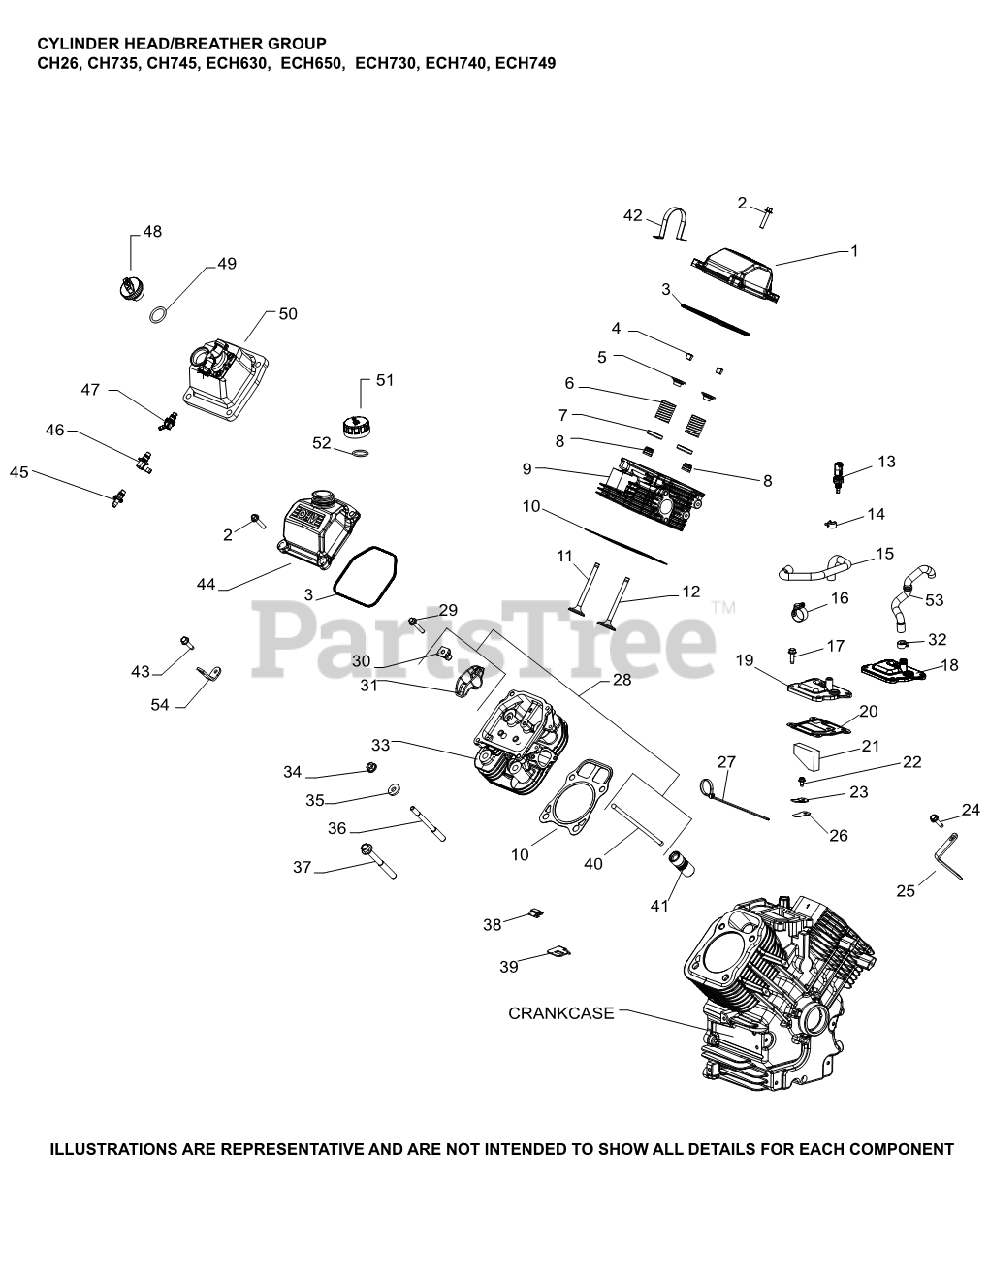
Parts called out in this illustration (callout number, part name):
1	KIT, VALVE COVER-PLAIN
2	SCREW, FLG M6X1.0X30
3	O-RING (YELLOW), VALVE COVER
4	KIT, RETAINER
5	CAP, VALVE SPRING
6	SPRING, VALVE
7	RETAINER, SPRING
8	SEAL, VALVE BAND
9	KIT, CYLINDER HEAD #1
10	KIT, CYLINDER HEAD GASKET
11	VALVE, EXHAUST
11	VALVE, EXHAUST (.25)
12	VALVE, INTAKE (STD)
12	VALVE, INTAKE (.25)
13	SENSOR, TEMPERATURE
17	SCREW, THREAD FORMING
18	KIT, BREATHER COVER USE 24 096 165-S
20	GASKET, BREATHER
21	FILTER, BREATHER
22	SCREW, FLG THD FRM M5X.8X10
23	RETAINER, REED
26	REED, BREATHER
28	KIT, VALVE TRAIN
29	SCREW, FLG M6X1.0X34
30	PIVOT, ROCKER ARM
31	ARM, ROCKER
32	CLAMP SPRING HOSE
33	KIT, CYLINDER HEAD #2
34	NUT, FLG M8X1.25
35	WASHER, FLAT 8.6 MM
36	STUD, M8X1.25
38	CLIP, O2 SENSOR
39	BRACKET, OXYGEN SENSOR
40	ROD, PUSH
41	LIFTER, VALVE HYDRAULIC - (#2535111S)
42	STRAP, BREATHER - USE 24 755 241-S
45	KIT, STRAIGHT FITTING
46	KIT, 90 DEG. FITTING
48	CAP ASSY, OIL FILL (YELLOW)
50	KIT, VALVE COVER-FUEL PUMP
